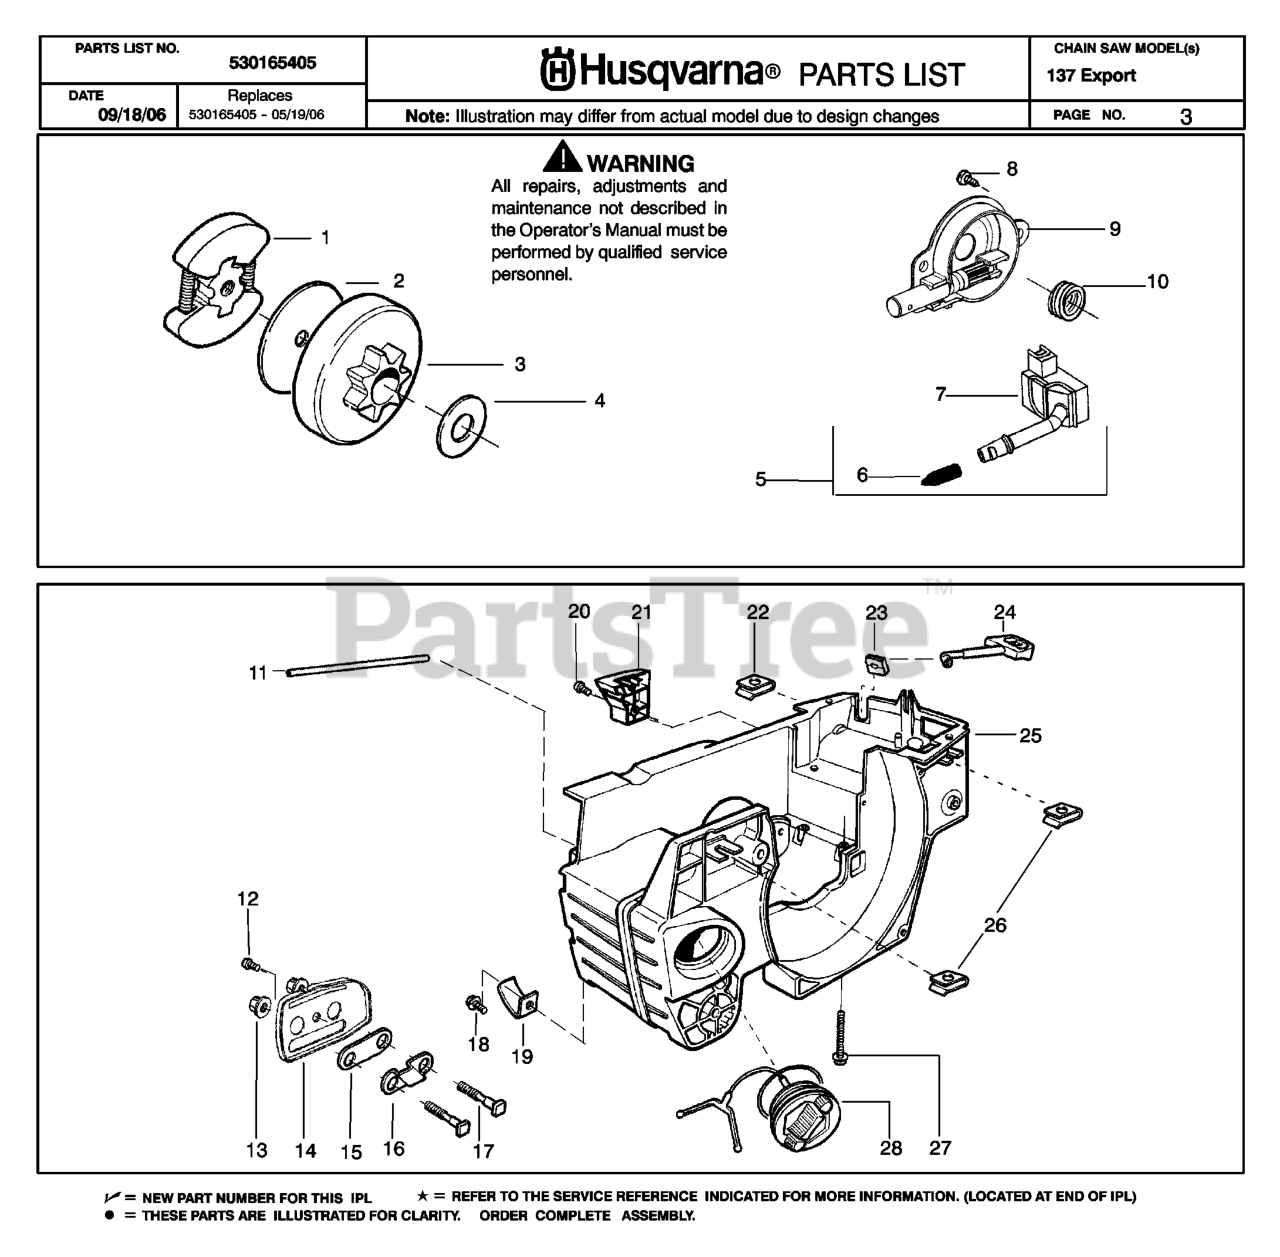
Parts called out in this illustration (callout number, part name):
1	COMPRESION SLEEVE/ISOLATOR SET
3	RP CLUTCH COVER
4	PROTECTION PLATE
5	SCREW
7	CRANKCASE
12	SCREW
